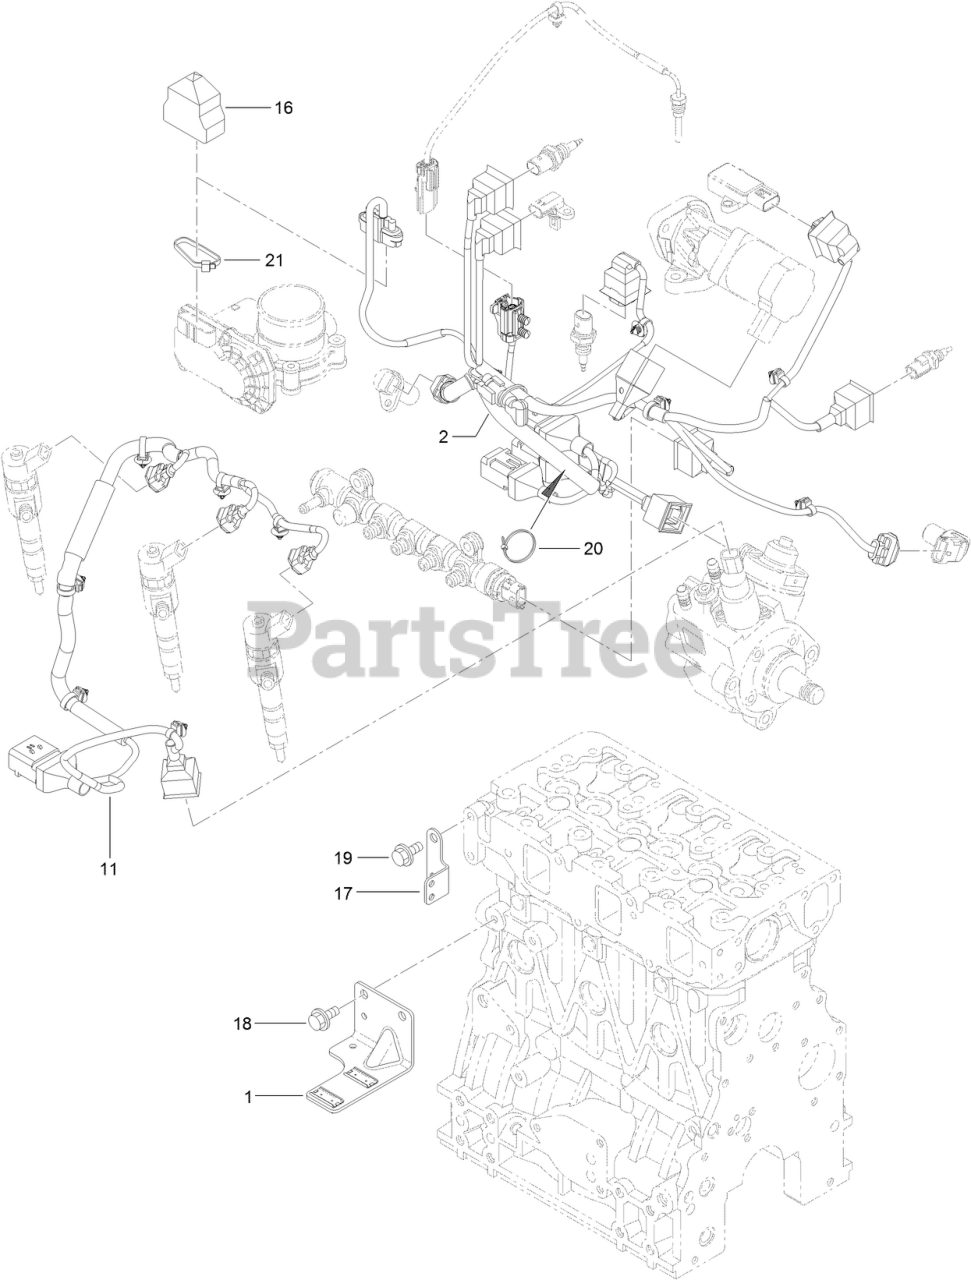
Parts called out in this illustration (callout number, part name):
1	BRACKET-CONNECTOR
2	HARNESS
11	HARNESS
16	BOOT-TYPE, CAP
17	BRACKET-HARNESS
